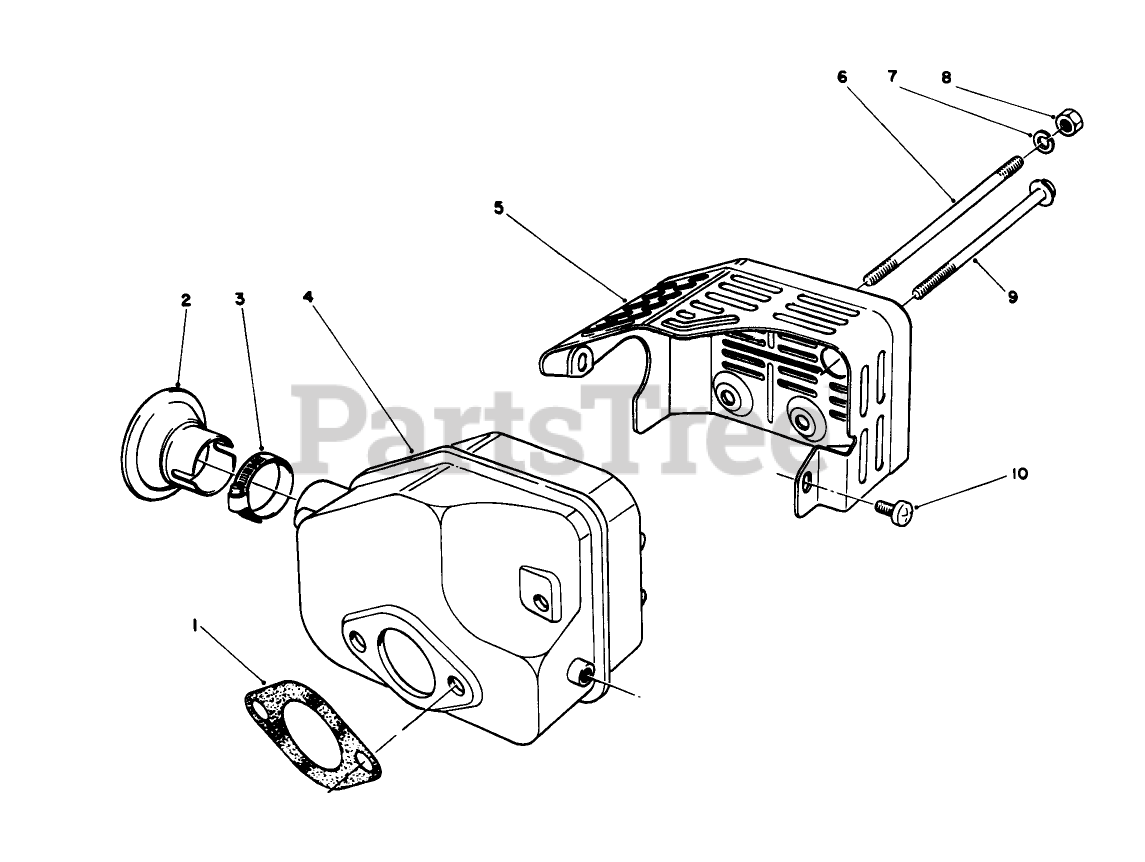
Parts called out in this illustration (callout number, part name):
1	GASKET
3	Clamp
4	MUFFLER
5	COVER-MUFFLER
7	WASHER-LOCK
10	SCREW
